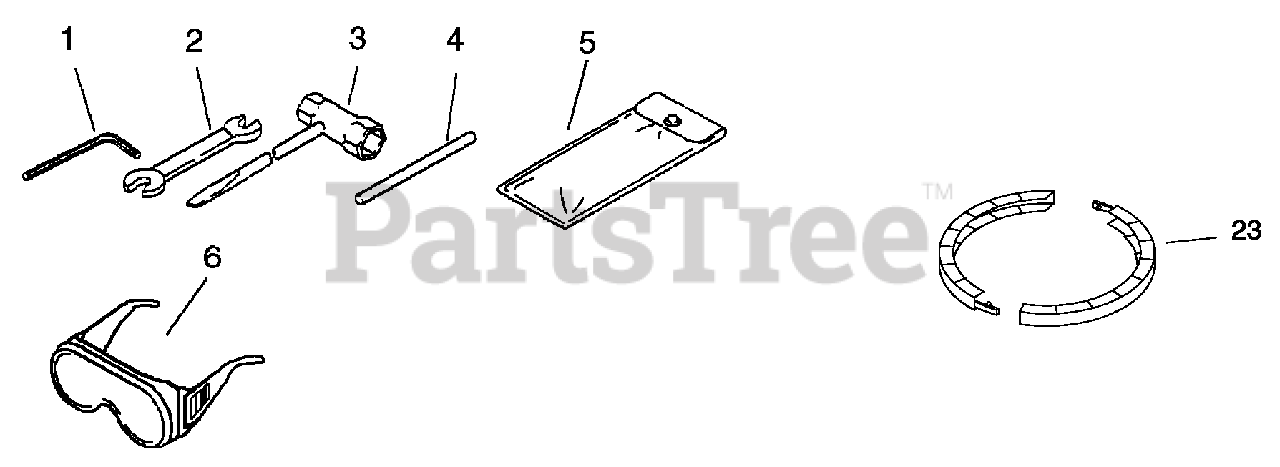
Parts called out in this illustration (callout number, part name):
1	HEX KEY - 4mm
2	SPANNER - 8X10mm
3	T-WRENCH - 17X19mm
4	ROD, LOCKING - 5X120mm
5	BAG, TOOL
6	GOGGLES
23	COVER, BLADE
